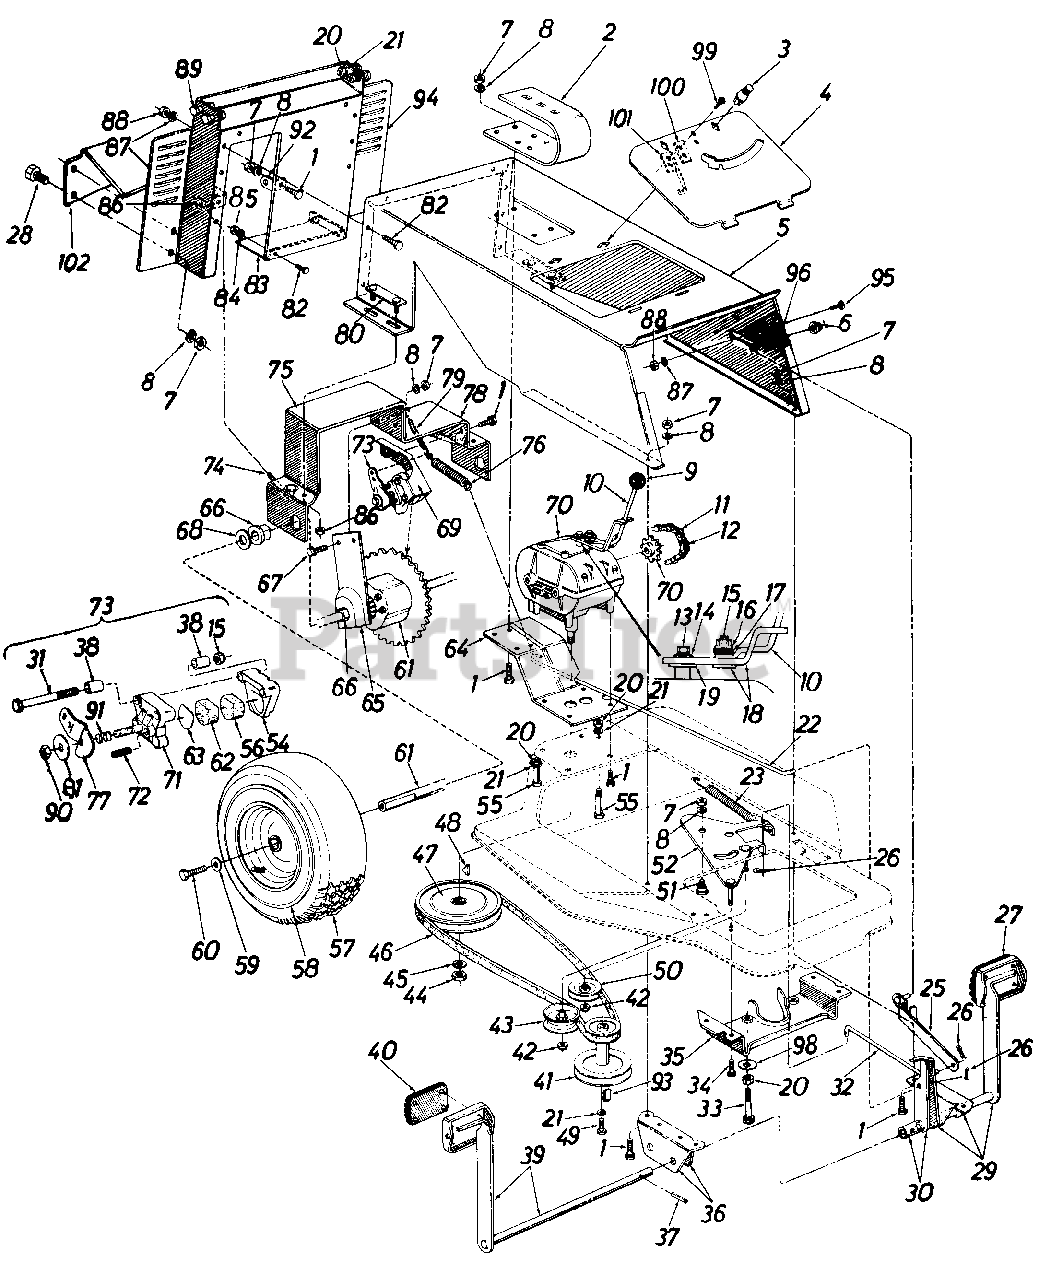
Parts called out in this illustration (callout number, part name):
1	Hex Sems Bolt 5/16-18 x .75" Lg.
2	Seat Spring
3	Fastener
4	Rear Frame Cover
5	Rear Frame
6	Push Cap .25" Dia.-Black
7	Hex Nut 5/16-18 Thd.*
8	L-Wash. 5/16" I.D.
9	Ball Knob
10	Shift Lever-Transmission
11	#420 Chain 1/2" Pitch x 77 Links
12	#420 Master Link
13	Hex Bolt 1/4-28 x .62" Lg.
14	Bell-Wash. .25" I.D. x .88 O.D. x .062"
15	Hex Cent. L-Nut 5/16-18 Thd.
16	Fl-Wash. .344" I.D. x.88" O.D.
17	Rubber Wash. .33" I.D. x .87"
18	ShiH Lever Brkt. Ass'y.
19	Hardened Wash. 1.0" O.D.
20	Hex Nut 3/8-16 Thd.
21	L-Wash. 7/16" I.D.
22	Brake Rod
23	Extension Spring
25	Clutch Lockout Ass'y.
26	Cotter Pin 3/32" Dia. x .75"
27	Clutch Pedal Pad
28	Hex Bolt 5/16-18 x .75" Lg.
29	Clutch Pedal & Brkt. Ass'y.
30	Brake Lever Ass'y.
31	Hex Bolt 5/16-18 x 2.5" Lg.
32	Clutch Rod
33	Hex Bolt 3/8-16 x 3.5" Lg.
34	Hex Sems Bolt 1/4-20 x .75"
35	Engine Belt Guard Ass'y.
36	Pedal "U" Brkt.-R.H.
37	Spring Pin Spiral .25" Dia. x 1.5" Lg.
38	Bushing
39	Brake Pedal Shaft Ass'y.
40	Brake Pedal Pad
41	Two-Step Engine Pulley
42	Hex Ins. L-Nut 3/8-24 Thd.
43	Fl-Idler w/Flanges 2.75" Dia.
44	Hex Jam Nut 1/2-20 Thd.
45	L-Wash. 1/2" I.D.
46	"V"-Belt
47	Transmission Split Pulley .50" I.D.
48	#4 Hi-Pro Key 3/32 x 5/8" Dia.
49	Hex Bolt 7/16-20 x 1.5" Lg.
50	"V"-Idler
51	Shld. Bolt .437" Dia. x .18"
52	Idler Brkt. Ass'y.
54	Casting-Carrier
55	1 Shld. Bolt .498" Dia. x 2.0"
56	Pad-Friction
57	Rear Wheel Ass'y.-Comp. 14.5 x 4.5
58	Rear Wheel Rim Only
59	Bell-Wash. .345 I.D. x .88
60	Hex Cent. Lock Scr. 5/16-24 x.75" Lg. H.T.
61	Differential Ass'y. Comp.
62	Pad-Fricion
63	Disc-Back-Up
64	Seat Support Ass'y.
65	Rear Axle Plate
66	Flange Brg. w/Flats .753" I.D.
67	Hex Sems Bolt 5/16-18 x 1.0" Lg.*
68	Fl-Wash. .812" I.D. x 1.38" O.D. x .10"
69	Disc Brake Brkt. Ass'y.
70	Transmission
71	Casting-Cam
72	Push Pin
73	Disc Brake Ass'y.-Comp.
74	Chain Adj. Link 5/16-18 x 4.38" Lg.
75	Rear Axle Brkt.-R.H.
76	Brake Spring
77	Cam Lever
78	Rear Axle Brkt.-L.H.
79	Brake Return Spring
80	Plate Ass'y. Axle Bolt
81	Washer
82	Truss Hd. Mach. Scr. #10-24 x.62" Lg.
83	Baffle Plate
84	Ext. L-Wash.
85	Hex Nut 10-24 Thd.
86	Hex Ins. L-Nut 5/16-18 Thd.
87	L-Wash. 1/4" I.D.
88	Hex Nut 1/4-20 Thd.
89	Shld Bolt .498" Dia. x .33"
90	Hex Top L-Nut
92	Chute Pivot Brkt.
93	Sq.-Key 1/4 x 2.0" Lg.
94	Grass Catcher Adapter
95	Hex Bolt 1/4-20 x .50" Lg.
96	Safety Switch
98	Belleville Washer
99	Hex Wash. Hd. Scr. #8 x .50"
100	Insulator Nut Plate
101	Spring Switch
102	Rear Chute Baffle
